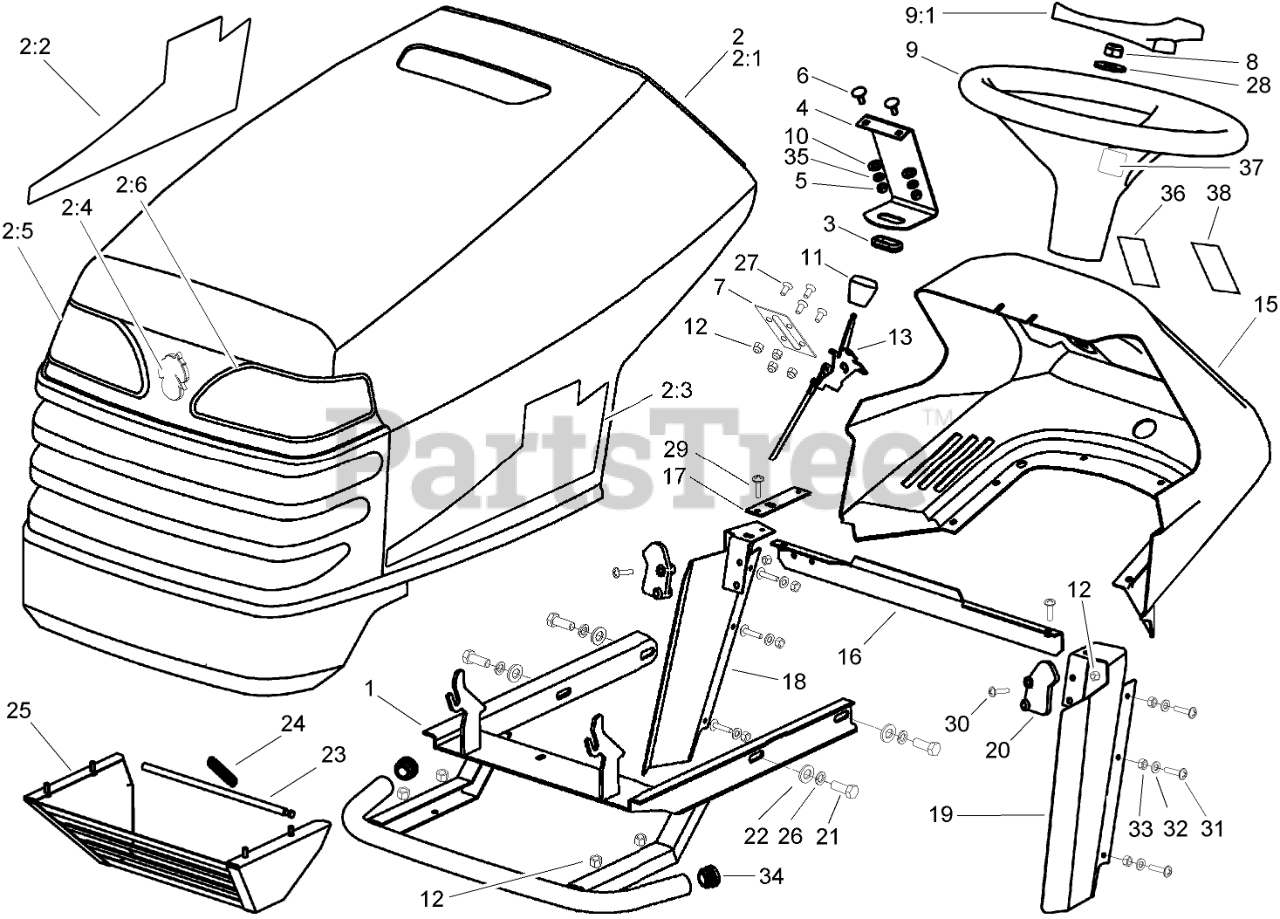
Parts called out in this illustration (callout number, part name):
1	SUPPORT-BUMPER
2	HOOD-ASSEMBLY
2:1	Hood
2:2	DECAL-HOOD, RH
2:3	DECAL-HOOD, LH
2:4	EMBLEM
2:5	LENS-HEADLAMP, RH
2:6	LENS-HEADLAMP, LH
3	BUSHING
4	HOLDER-TANK, FUEL
5	NUT-LOCK
8	NUT-LOCK
9	WHEEL-STEERING
9:1	COVER-WHEEL, STEERING
10	WASHER-PLAIN
12	NUT-LOCK
13	CABLE-THROTTLE and CHOKE
15	PANEL-DASH
17	BRACKET
18	PANEL-RIGHT
19	PANEL-LEFT
20	LATCH-HOOD
21	SCREW-HH
22	WASHER-PLAIN
23	BAR-SAFETY
24	SPRING-HOOD
25	GUARD-MUFFLER
26	WASHER-LOCK, SPRING
28	Washer
32	WASHER
33	NUT-HEX
34	PLUG-END, TUBE
35	WASHER-LOCK, SPRING
36	DECAL-DASH THROTTLE and IGNITION
37	DECAL
38	DECAL-PTO
